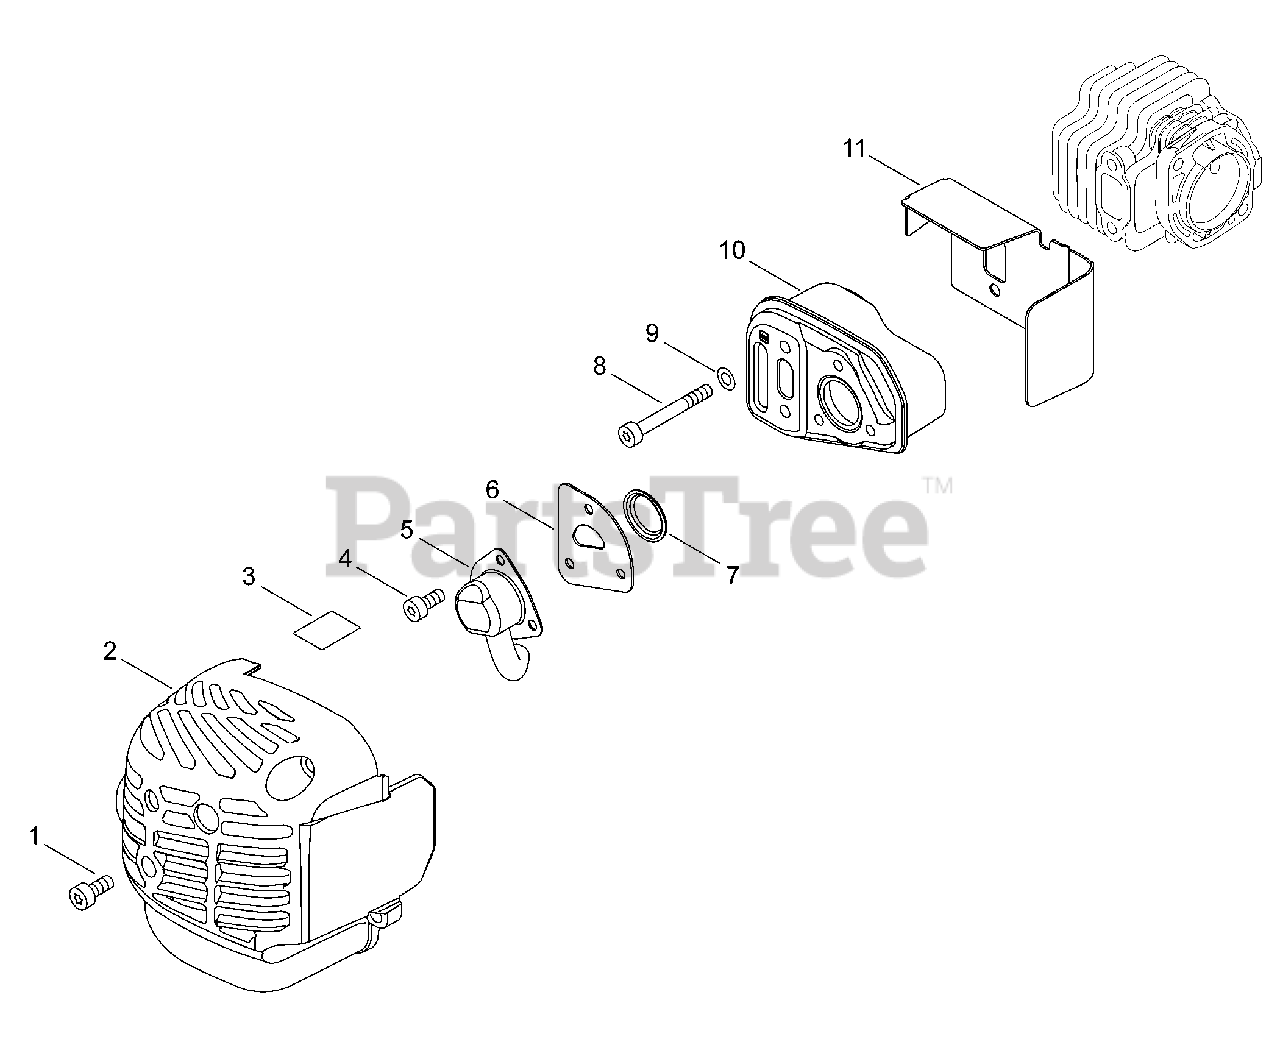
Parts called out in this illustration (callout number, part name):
1	BOLT, TORX 5
2	COVER, MUFFLER
3	LABEL, CAUTION - HOT
4	BOLT, TORX 4×8
5	GUIDE, EXHAUST
6	GASKET, EXHAUST
7	SCREEN, SPARK ARRESTER
8	BOLT, TORX 5×55
9	WASHER 5.5×12×0.8
10	MUFFLER
11	HEAT SHIELD, EXHAUST
